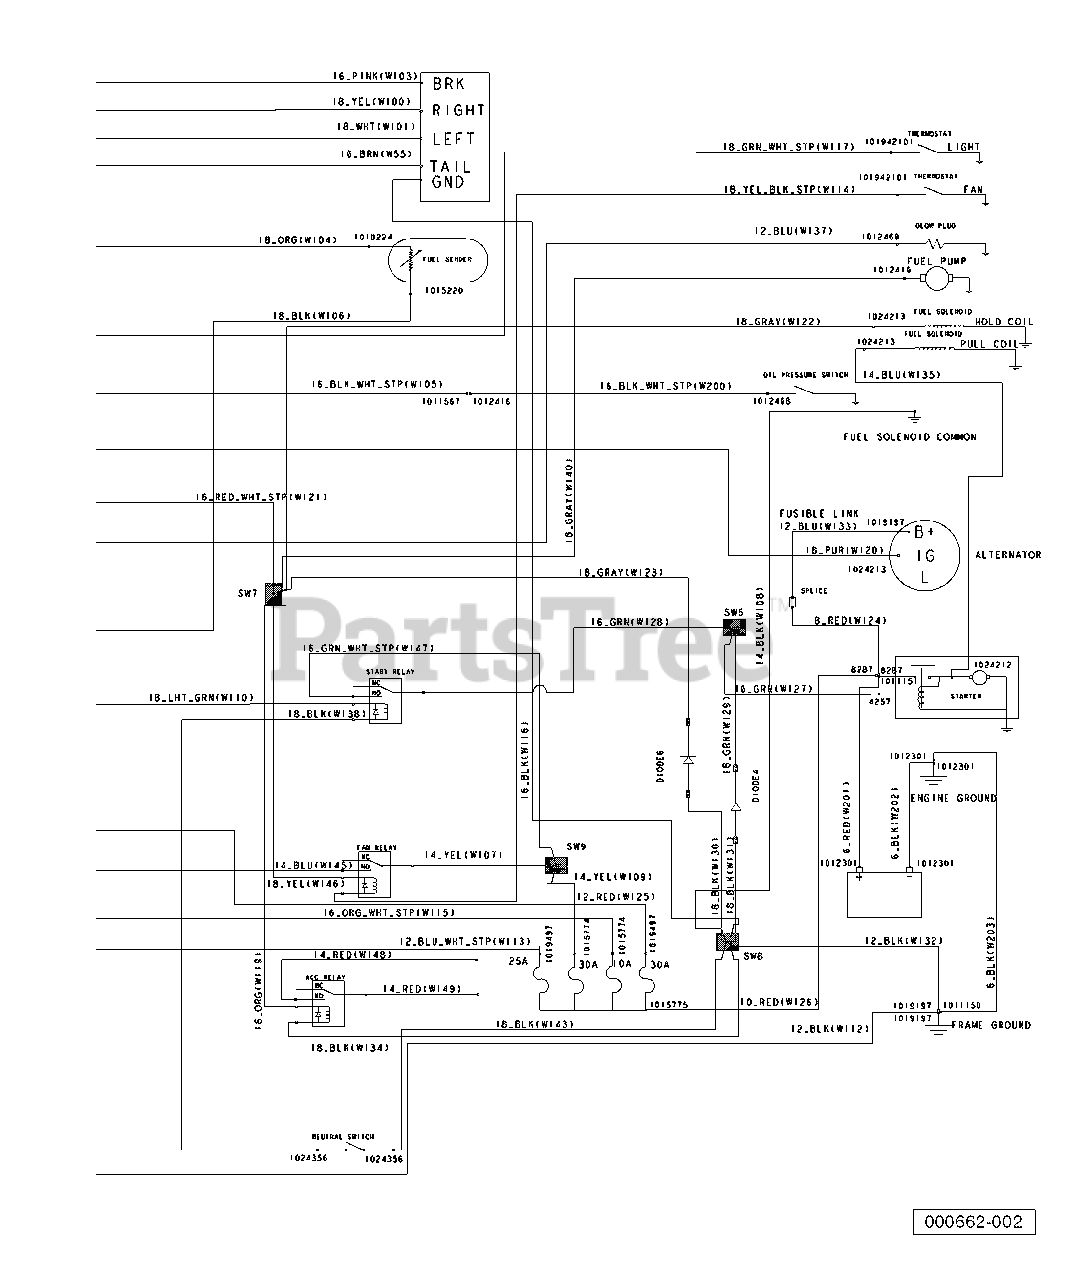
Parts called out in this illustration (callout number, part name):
1	Diode, General Purpose, 6.0a
2	Harness, Diesel AWD
3	Asm, Switch, Limit, Awd
